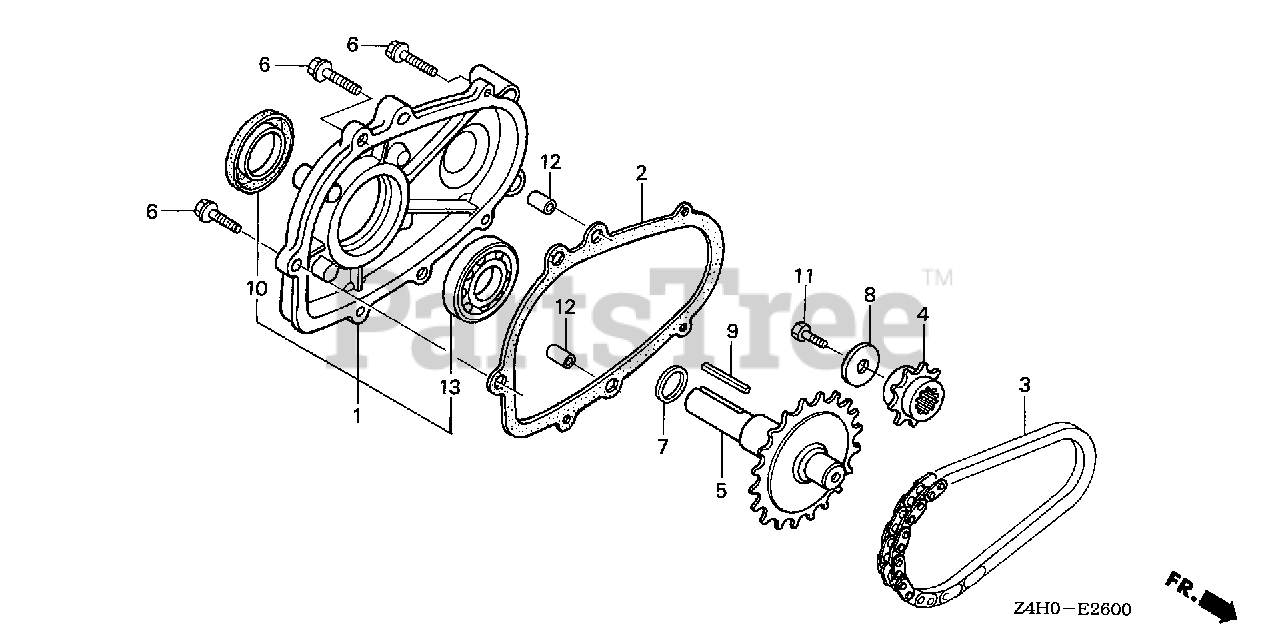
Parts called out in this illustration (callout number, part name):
1	COVER ASSY., CHAIN CASE
2	GASKET, CHAIN CASE COVER
3	CHAIN, P.T.O. DRIVE (DID270S-DHA-36LE)
4	SPROCKET, DRIVE (14T)
5	SHAFT, P.T.O. (28T)
6	BOLT, FLANGE (6X28) (CT200) Use up to Engine SN 1530314.
7	SPRING, THRUST
8	WASHER (8MM)
9	KEY (5X5X33)
10	OIL SEAL (25X41X6)
11	BOLT, HEX. (8X25)
12	PIN A, DOWEL (8X14)
13	BEARING, RADIAL BALL (6205)
